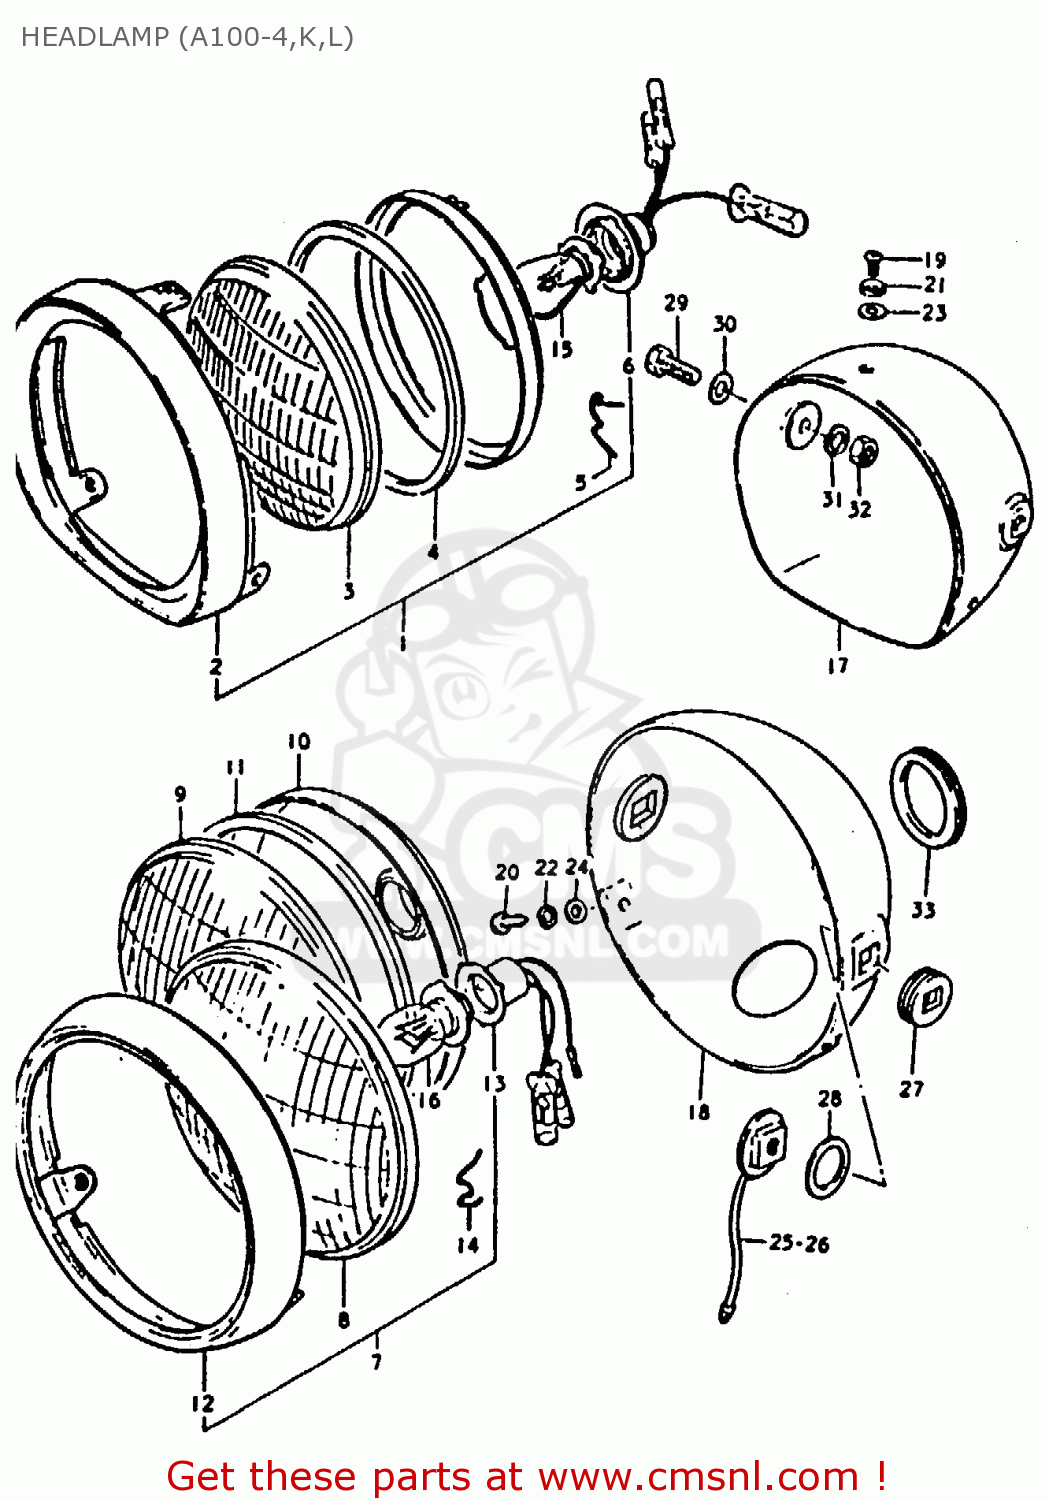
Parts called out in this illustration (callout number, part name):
1	HEADLAMP ASSY
2	RIM
3	LENS
4	GASKET
5	SPRING,HEAD LAMP UNIT
6	SOCKET
7	HEADLAMP ASSEMBLY
8	UNIT
9	LENS,HEADLAMP
10	REFLECTOR
11	GASKET (NAS)
12	RIM,HEADLAMP
13	SOCKET
14	SPRING
15	BULB(6V25/25W,STANLEY,A7007)
16	BULB
17	HOUSING, HEADLAMP
18	HOUSING, HEADLAMP
19	SCREW
20	SCREW
21	WASHER
22	LOCK WASHER
23	WASHER(4X12.5X0.3)
24	WASHER
25	SPACER, HOUSING RH
26	SPACER
27	CUSHION,HEADLAMP HOUSING
28	WASHER,HEADLAMP HOUSING
29	BOLT
30	WASHER
31	LOCK WASHER
32	NUT
33	GROMMET,HEADLAMP HOUSING
